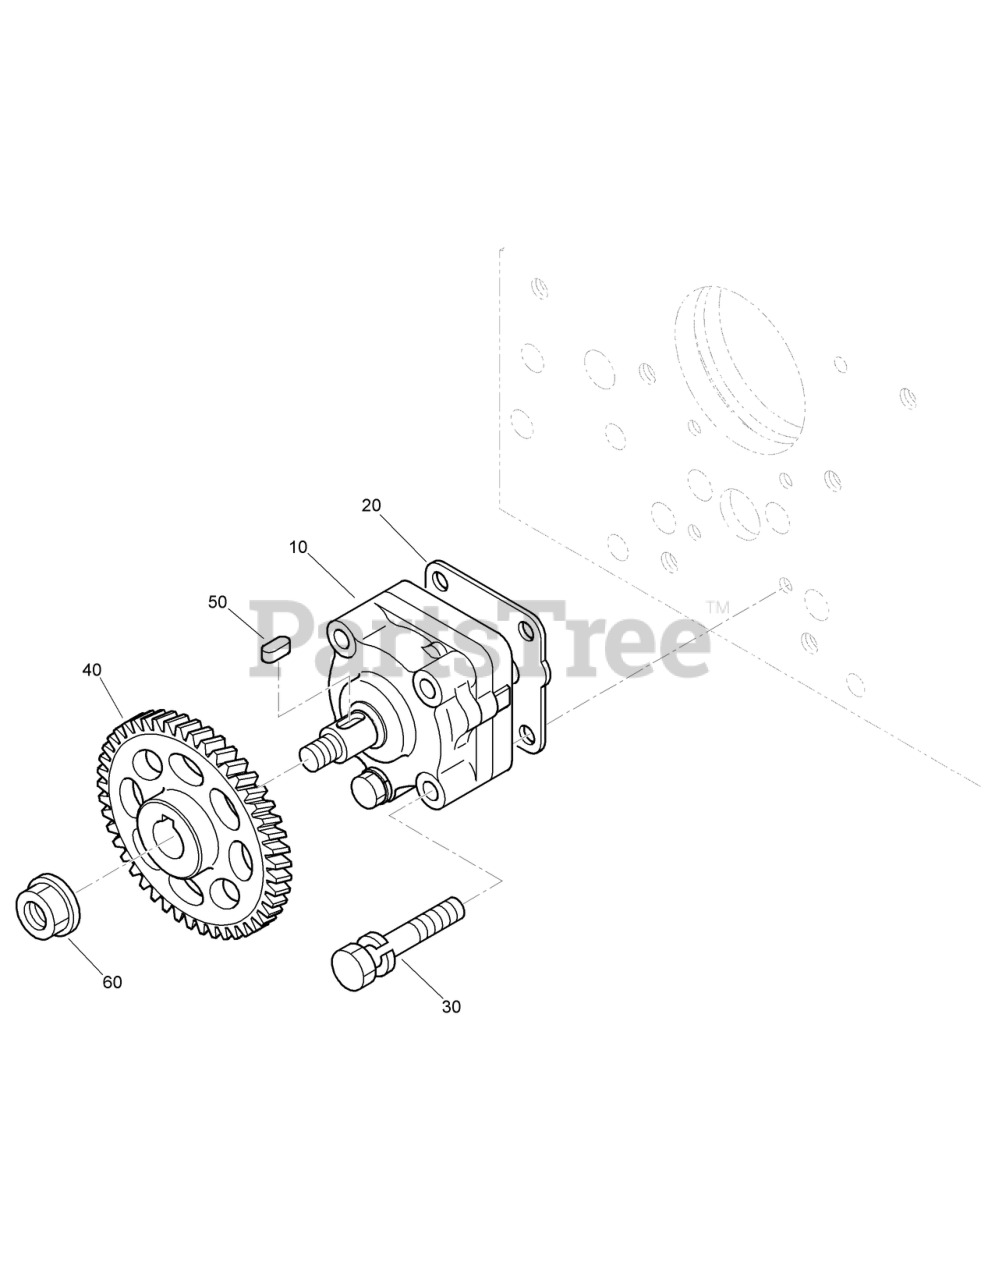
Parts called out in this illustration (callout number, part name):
10	OIL-PUMP
20	GASKET-PUMP, OIL
30	BOLT-SEMS
40	GEAR-DRIVE, OIL PUMP
50	KEY-FEATHER
